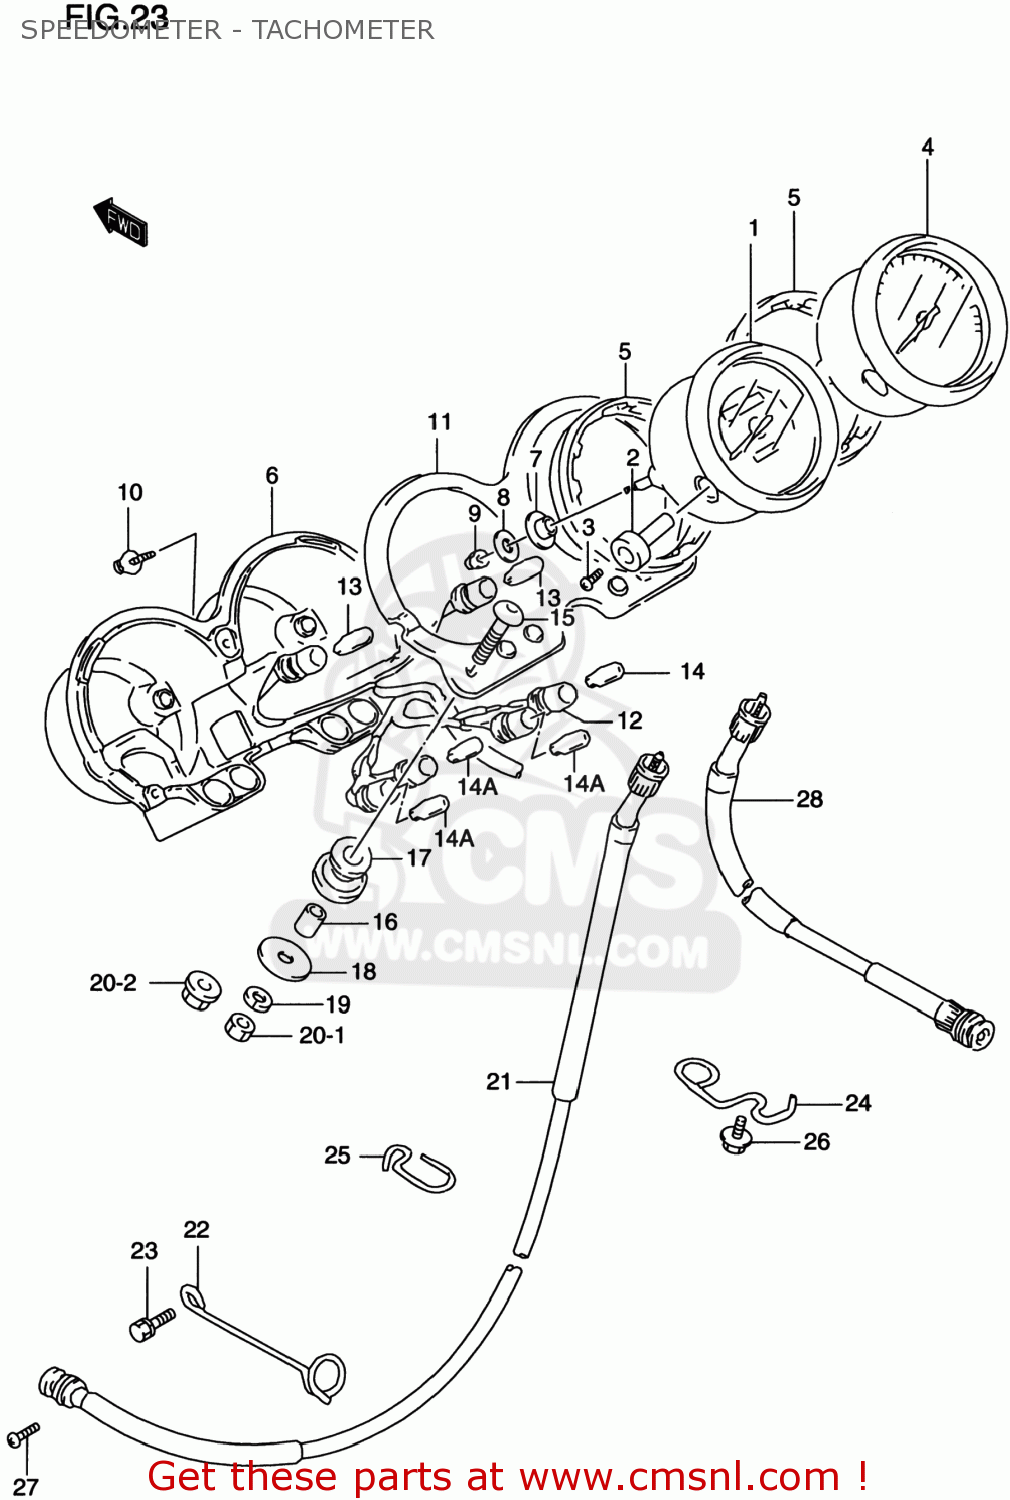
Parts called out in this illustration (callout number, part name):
1	SPEEDOMETER(MILE/KILO)
2	KNOB,TRIP
3	SCREW(2X6)
4	TACHOMETER
5	DAMPER
6	COVER
7	CUSHION
8	WASHER(5.5X16X1.2)
9	NUT
10	SCREW
11	BRACKET,METER
12	SOCKET
13	BULB(12V3.4W,T10)
14	BULB(12V1.7W,T10)
14A	BULB(12V3.4W,T10,BF175-01450A)
15	BOLT(6X30)
16	SPACER(6.5X10X15.7)
17	CUSHION,METER BRACKET
18	WASHER(6.5X28X1.6)
19	LOCK WASHER
20	NUT
21	CABLE ASSY,SPEEDOMETER
22	CLAMP,SPEEDOMETER CABLE
23	BOLT
24	GUIDE,SPEEDOMETER CABLE NO.2
25	GUIDE,SPEEDOMETER CABLE NO.3
26	BOLT
27	SCREW
28	CABLE ASSY,TACHOMETER
